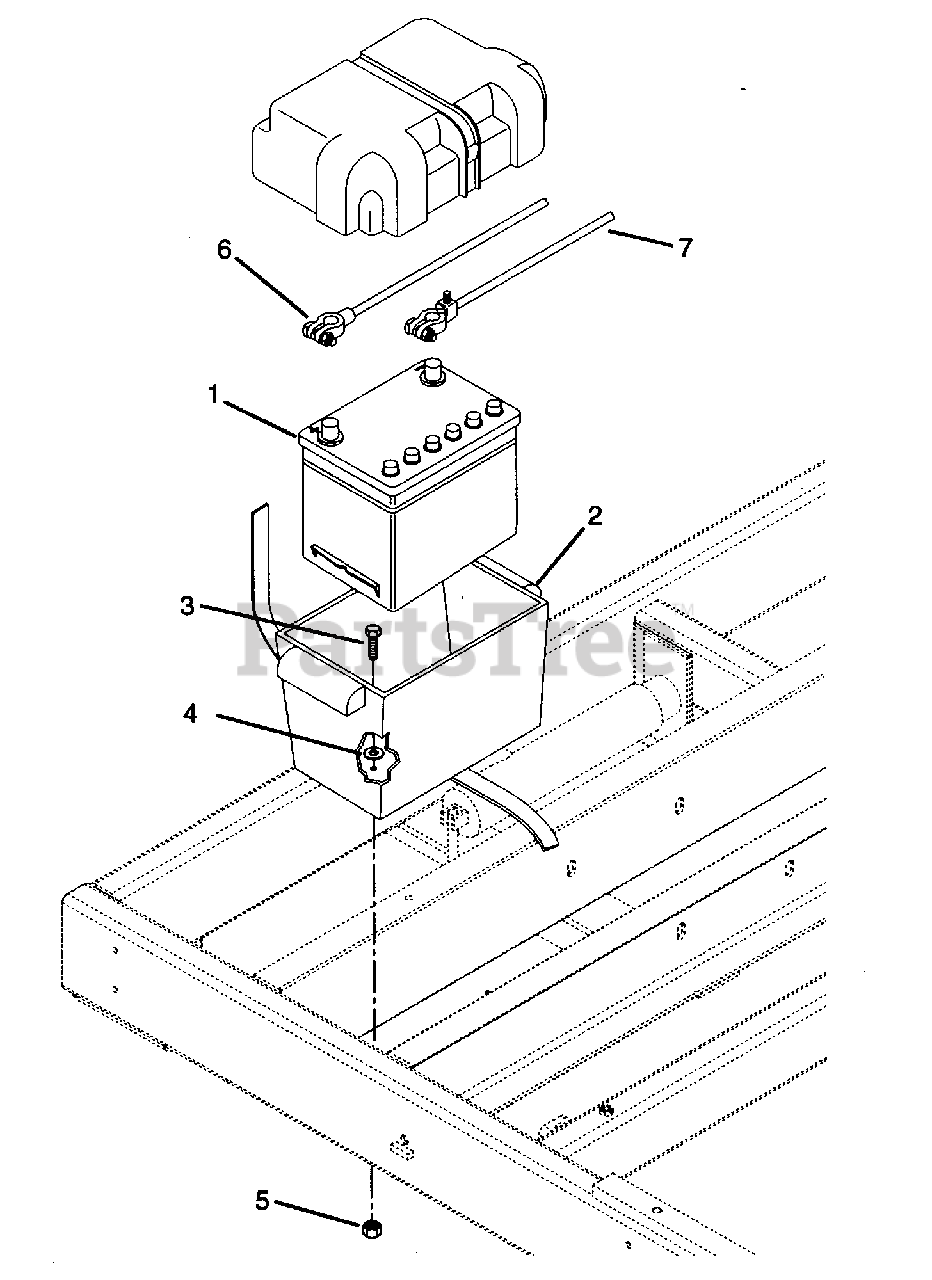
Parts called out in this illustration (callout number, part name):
2	Battery Box
3	Bolt-Hex .25-20 x .75
4	Washer-Flat-Steel .312 x .734 x .065
5	Nut .250-20
6	Battery Cable
7	Ground Cable
